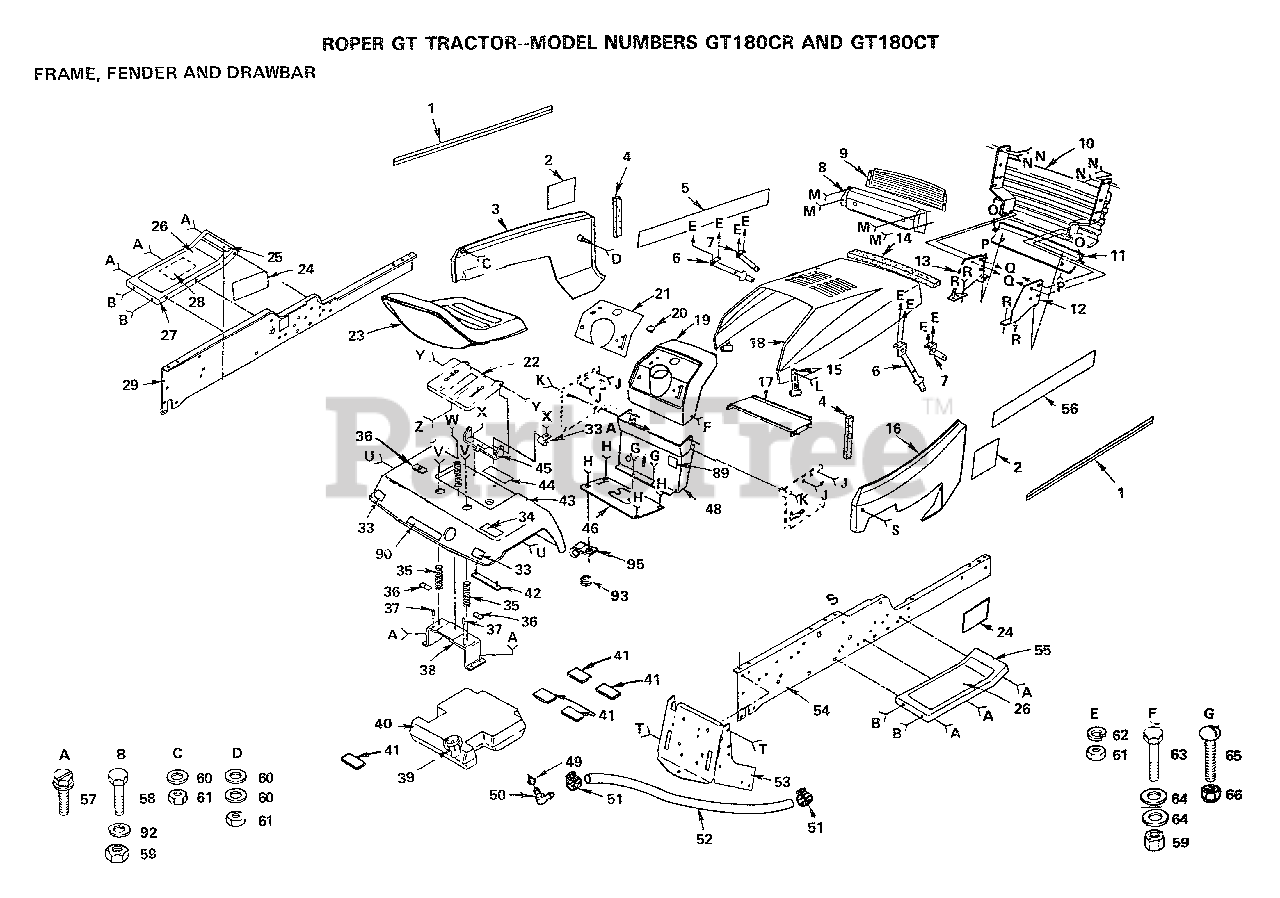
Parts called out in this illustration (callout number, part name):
4	FOAM STRIP HYT
9	LENS LT
12	SUPPORT-GRILL
13	SUPPORT-GRILL
14	FOAM-STRIP LT
20	PLUG-DASH T
21	DECAL-DASHBOARD
22	SEAT PAN T
25	DECAL T
28	DECAL T
33	REFLECTOR-TAIL YT
33A	CLIP T
34	DECAL-CAUTION
36	"CLAMP, SPRING LT"
37	NUT-PUSH YT
41	PAD-SPACER LT
45	BRACKET T
48	DASH ASSEMBLY
49	BUSHING OUTLET T
50	FUEL TANK STEM GT
57	SCREW
60	WASHER PM
63	BOLT
64	WASHER
65	SCREW
87	WASHER
89	DECAL, INSTRUCTION
91	SPRING T
92	WASHER
93	GROMMET T
94	SCREW GTV
